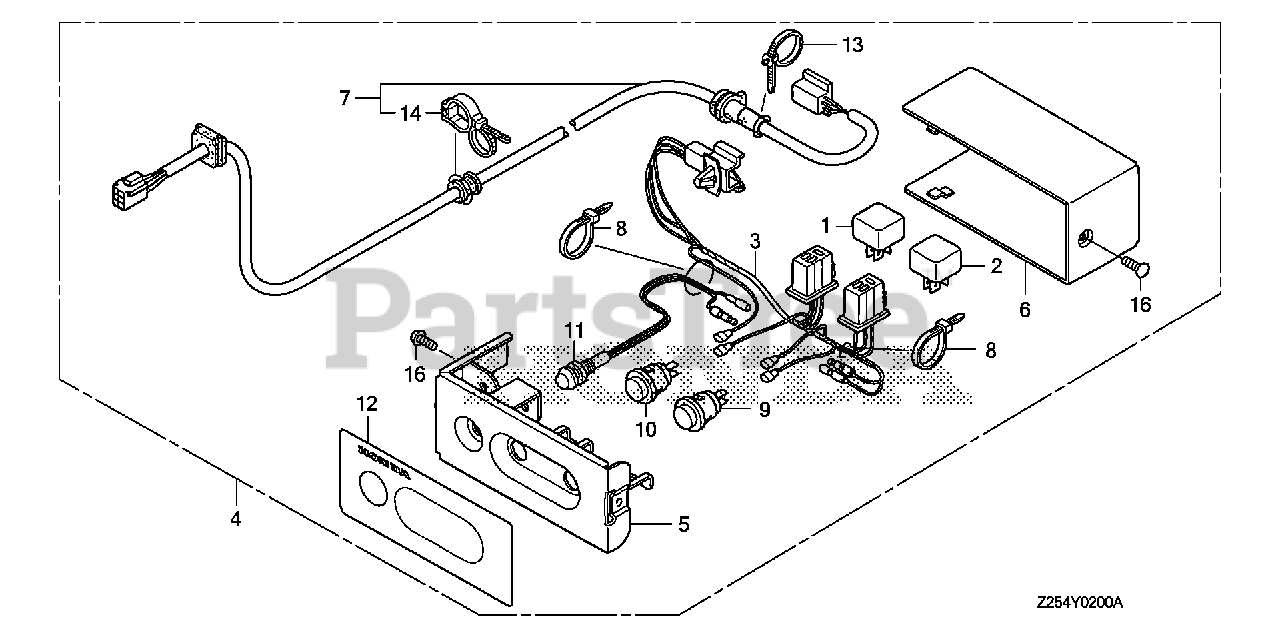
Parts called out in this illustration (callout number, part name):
1	RECTIFIER, SILICON
2	RECTIFIER, SILICON
3	HARNESS ASSY., REMOTE CONTROL
4	BOX ASSY., REMOTE CONTROL (10M) *NH105* (MAT BLACK)
4	BOX ASSY., REMOTE CONTROL (20M) *NH105* (MAT BLACK)
4	BOX ASSY., REMOTE CONTROL (30M) *NH105* (MAT BLACK)
5	PANEL, REMOTE CONTROL *NH105* (MAT BLACK)
6	COVER, REMOTE CONTROL *NH105* (MAT BLACK)
7	CABLE ASSY., REMOTE CONTROL (10M)
7	CABLE ASSY., REMOTE CONTROL (20M)
7	CABLE ASSY., REMOTE CONTROL (30M)
8	TIE, CABLE (C)
9	SWITCH, ENGINE STOP
10	SWITCH, START
11	LED ASSY.
12	MARK, REMOTE CONTROL
13	BAND, HARNESS (98MM) (NATURAL)
14	CLIP, TUBE (135MM) (BLACK)
16	SCREW, PAN (4X8)
